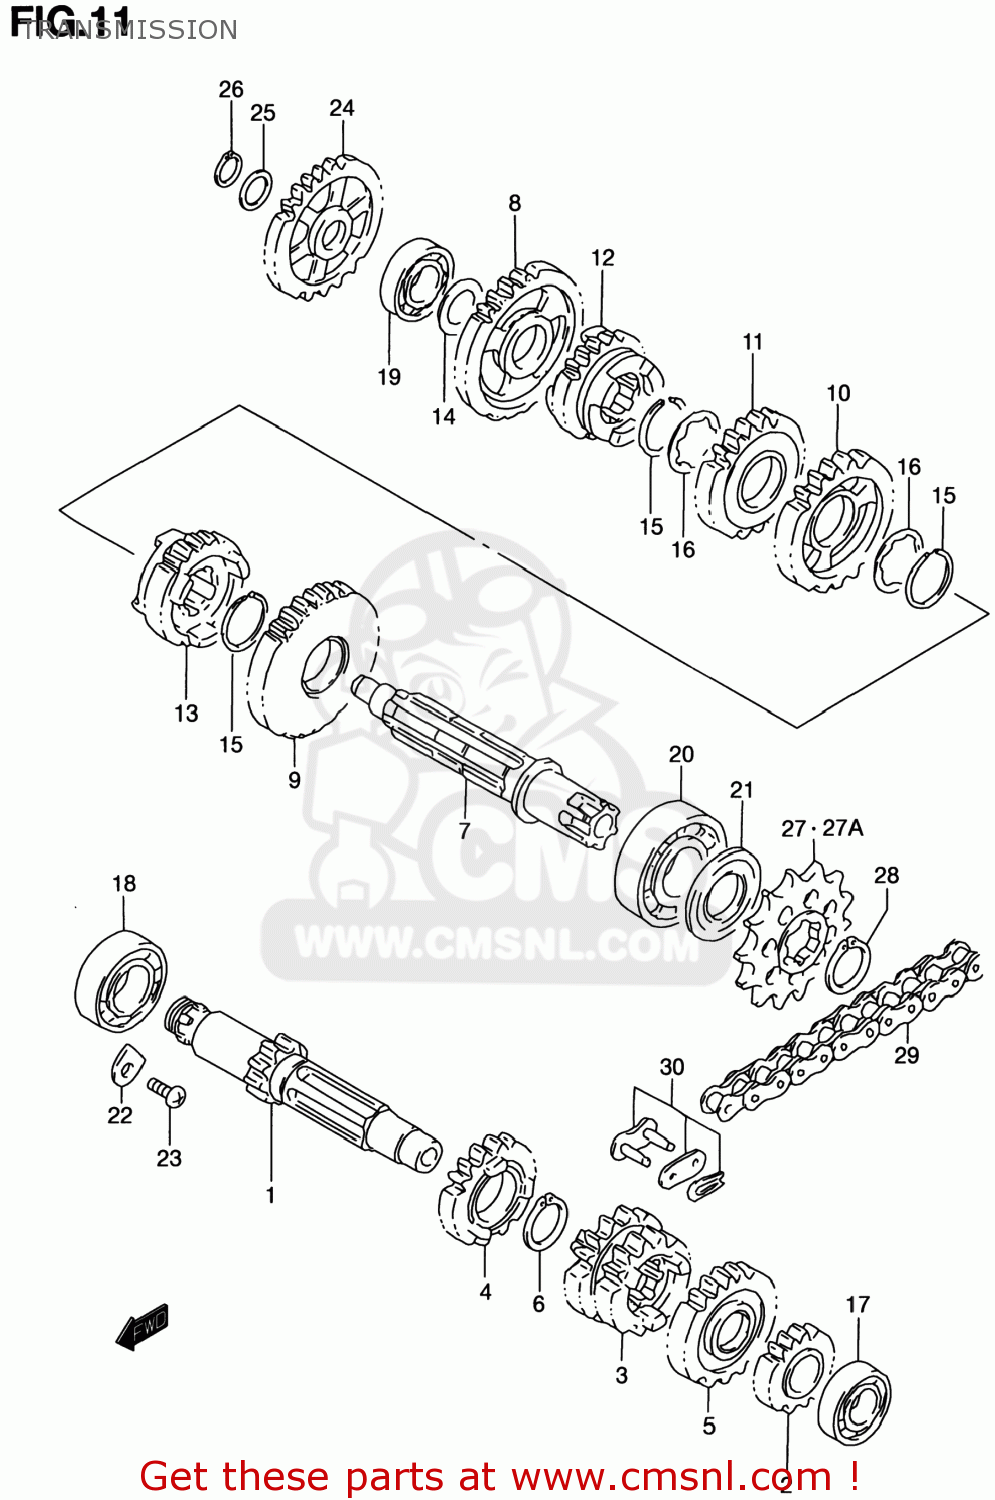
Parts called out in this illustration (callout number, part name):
1	SHAFT,COUNTER(NT:11)
2	GEAR,2ND DRIVE(NT:15)
3	GEAR,3RD & 4TH DRIVE(NT:14/15)
4	GEAR,5TH DRIVE(NT:18)
5	GEAR,6TH DRIVE
6	CIRCLIP
7	SHAFT,DRIVE
8	GEAR,1ST DRIVEN(NT:28)
9	GEAR,2ND DRIVEN(NT:29)
10	GEAR,THIRD DRIVEN (NT:22)
11	GEAR,FOURTH DRIVEN (NT:20)
12	GEAR,5TH DRIVEN(NT:21)
13	GEAR,6TH DRIVEN(NT:23)
14	SHIM(15X26X1)
15	CIRCLIP
16	WASHER,LOCK
17	BEARING
18	BEARING(20X42X12)
19	BEARING
20	BEARING(20X47X14)
21	OIL SEAL (20X35X5)
22	RETAINER
23	SCREW
24	GEAR,KICK STARTER IDLE(NT:24)
25	SHIM(12X20X0.5)
26	CIRCLIP,12 MM
27	SPROCKET,ENGINE(NT:14)
27A	SPROCKET,ENGINE(NT:13)
28	CIRCLIP
29	CHAIN,DRIVE(428G2X118L)
30	JOINT SET,CHAIN
